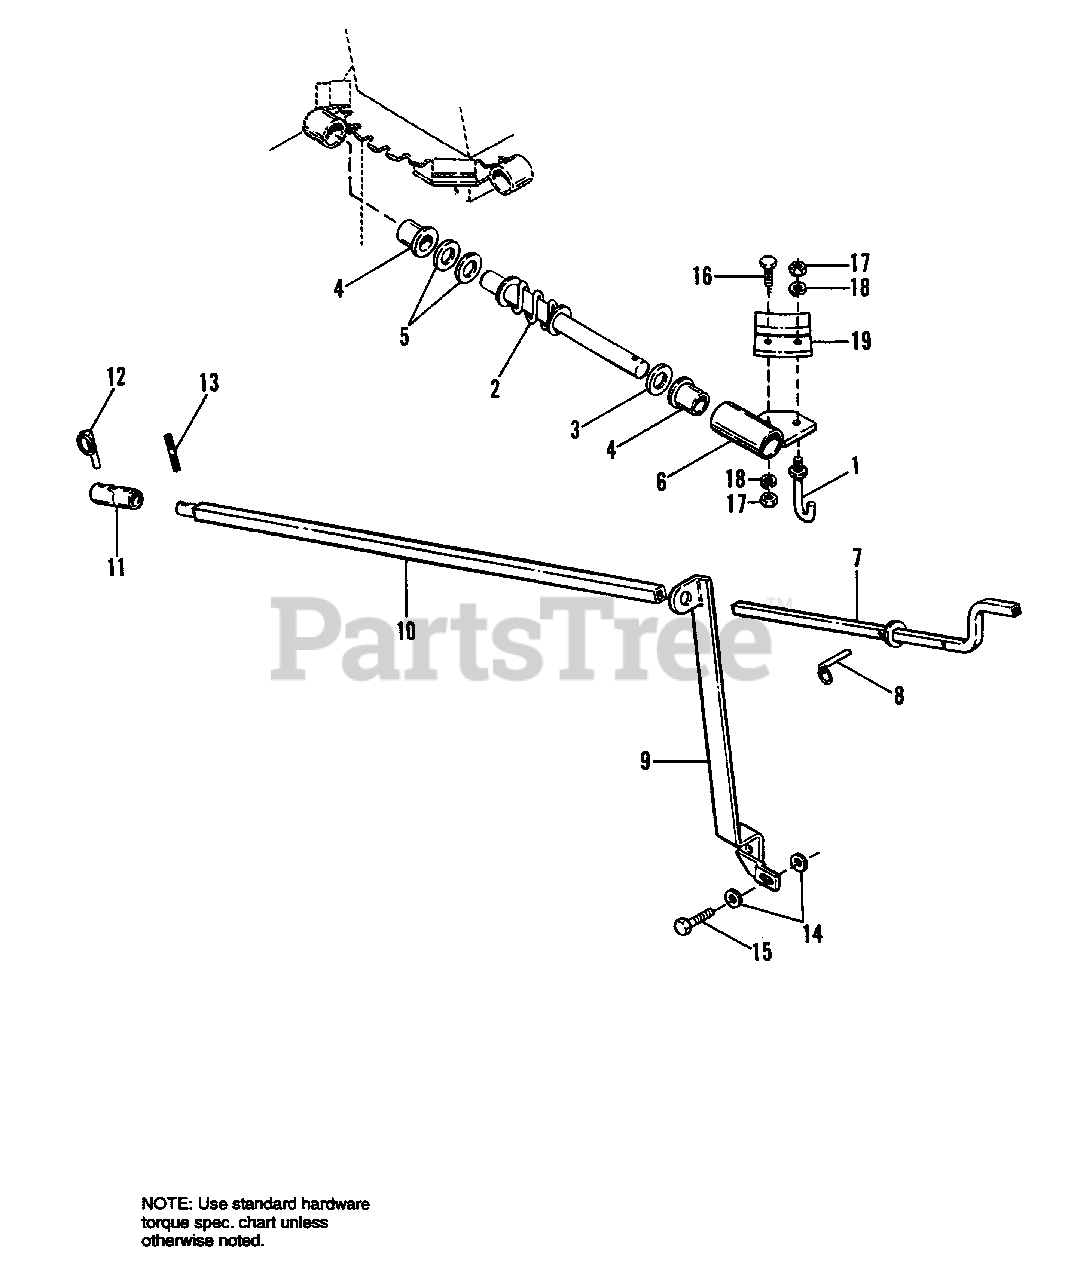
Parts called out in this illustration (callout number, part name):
2	WIRE, Coil Assembly
3	WASHER, 25/32 x 1-3/8 x .075
4	BUSHING, Turn collar
5	WASHER, 3/4 flat
6	BRACKET, Wire coil support
7	HANDLE, Crank ASSEMBLY
8	PIN, Detent ring 3/16 x 1
9	BRACKET, Handcrank pivot
10	TUBE, Crank ASSEMBLY
11	JOINT, Universal, w/holes
12	PIN, Detent ring, 5/16 x 1-1/8
13	PIN, Roll, 5/16 x 1-1/2
14	WASHER, 13/32 x 7/8 x 5/64
15	CAPSCREW, Hex Hd., 3/8-16 x 1-1/2
16	CAPSCREW, Hex Hd., 1/4-20 x 1
17	NUT, Hex, 1/4-20
18	LOCKWASHER, 1/4
19	RETAINER, Chute
